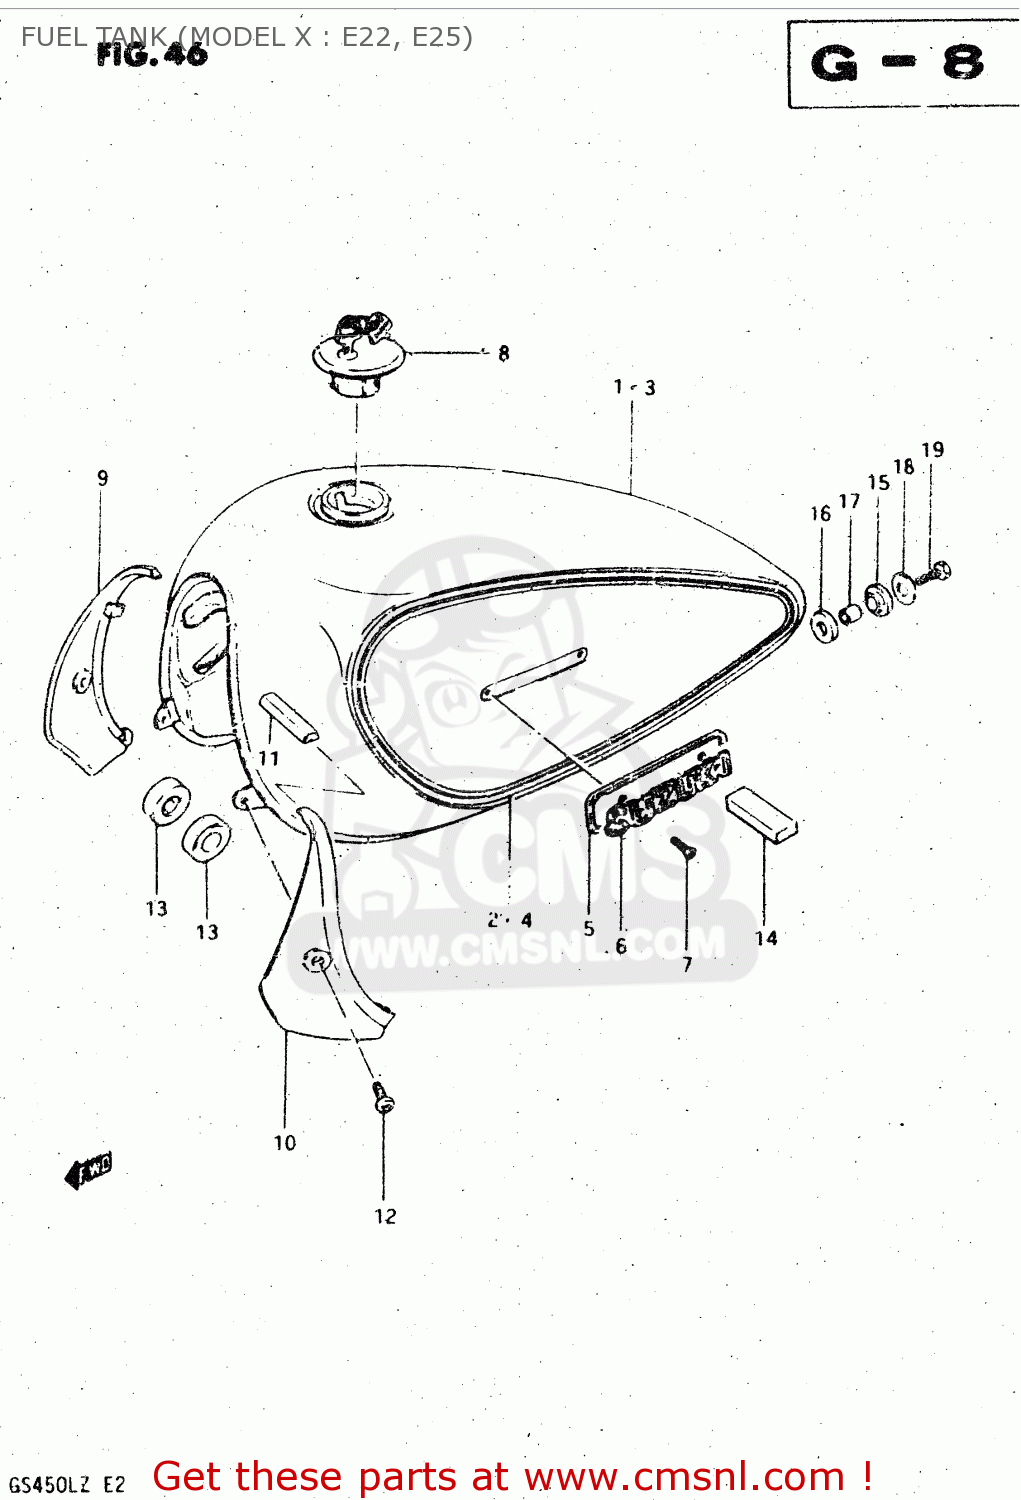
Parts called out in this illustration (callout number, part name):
1	TANK ASSEMBLY,FUEL
2	TAPE SET,FUEL TANK STRIPE
3	TANK ASSEMBLY,FUEL
4	TAPE SET,FUEL TANK
5	CUSHION
6	EMBLEM,FUEL TANK
7	SCREW 3X6
8	CAP SET,FUEL TANK
9	COVER,FUEL TANK,FRONT,RIGHT
10	COVER,FUEL TANK,FRONT,LEFT
11	TUBE, FRONT
12	SCREW 6X12
13	CUSHION
14	CUSHION
15	CUSHION
16	CUSHION
17	SPACER(8.5X12X19)
18	WASHER (8.5X29X1.6)
19	BOLT (8X30)
